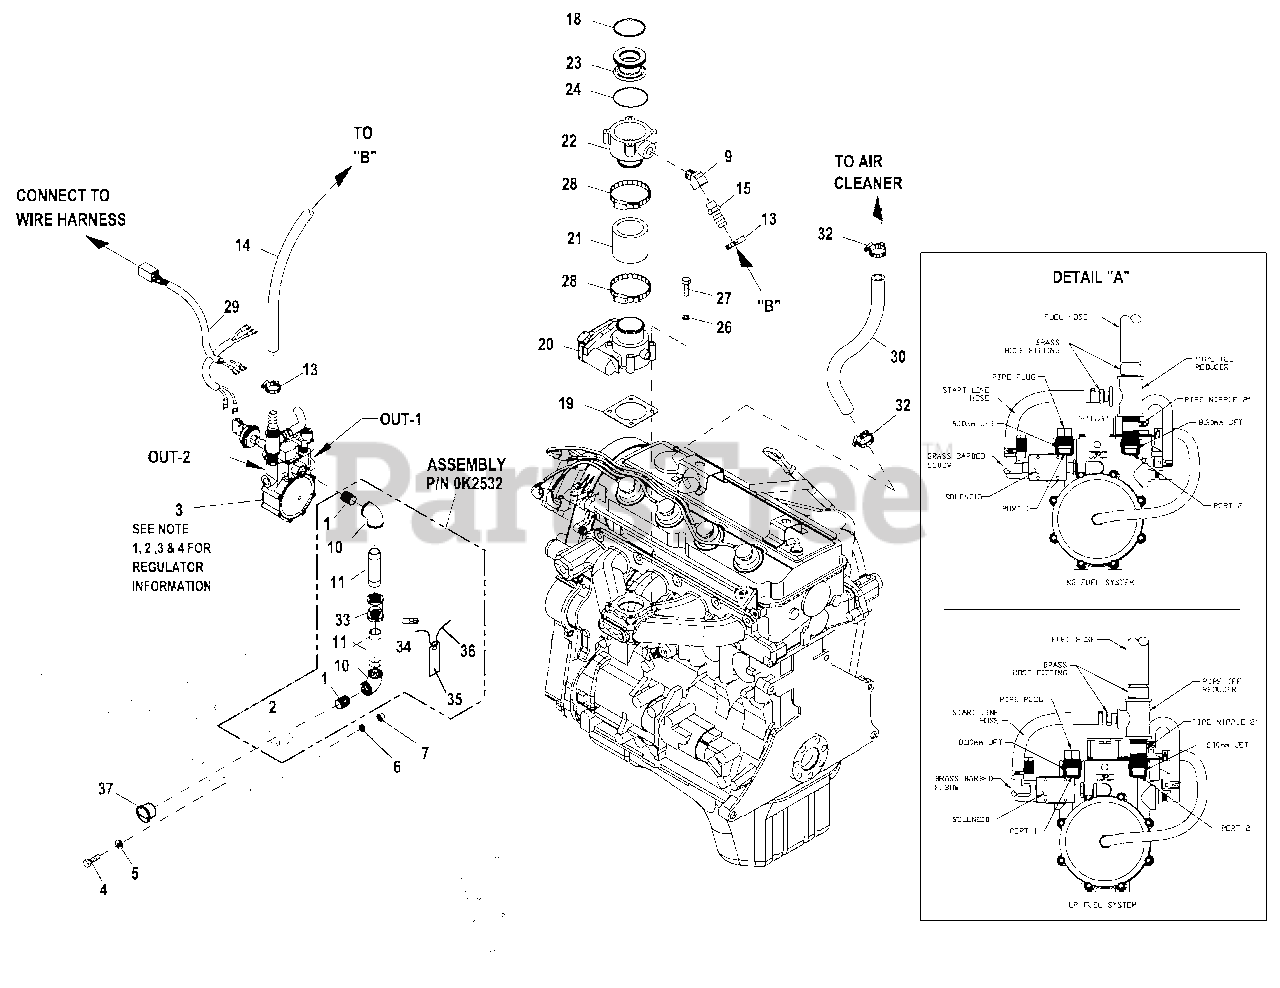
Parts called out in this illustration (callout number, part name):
1	MUFFLER 7" X 9" X 18-1/2" 2" IN/OUT
2	EXHAUST ELBOW 2 1/4 OD 2 1/2OD
3	BRACKET MUFFLER
4	MUFFLER BRACKET STIFFENER
5	MUFFLER STRAP
6	BOLT U 3/8-16 X 2.62
7	EXHAUST BLANKET 988MM (C2)
8	SCREW THF M6-1 X 16 N WA Z/JS
9	PIPE EXHAUST G2
10	DIFFUSER EXHAUST WELDMENT
11	GASKET EXHAUST RING
12	WASHER LOCK 3/8 SS
13	SCREW HHC 3/8-16 X 1-3/4 SS
14	EXHAUST FLANGE 2" PIPE
15	SCREW HHC M6-1.0 X 35 G8.8 BLK
16	WASHER LOCK M6-1/4
17	WASHER FLAT 1/4-M6 ZINC
18	BOLT U 5/16-18 X 2.25
19	NUT HEX 5/16-18 STEEL
20	WASHER LOCK M8 SS
21	WASHER FLAT 3/8 SS
22	NUT HEX 3/8-16 STEEL
23	WASHER LOCK 3/8 SS
24	PIPE EXHAUST CROSSOVER
25	PIPE EXHAUST MUFFLER OUT
